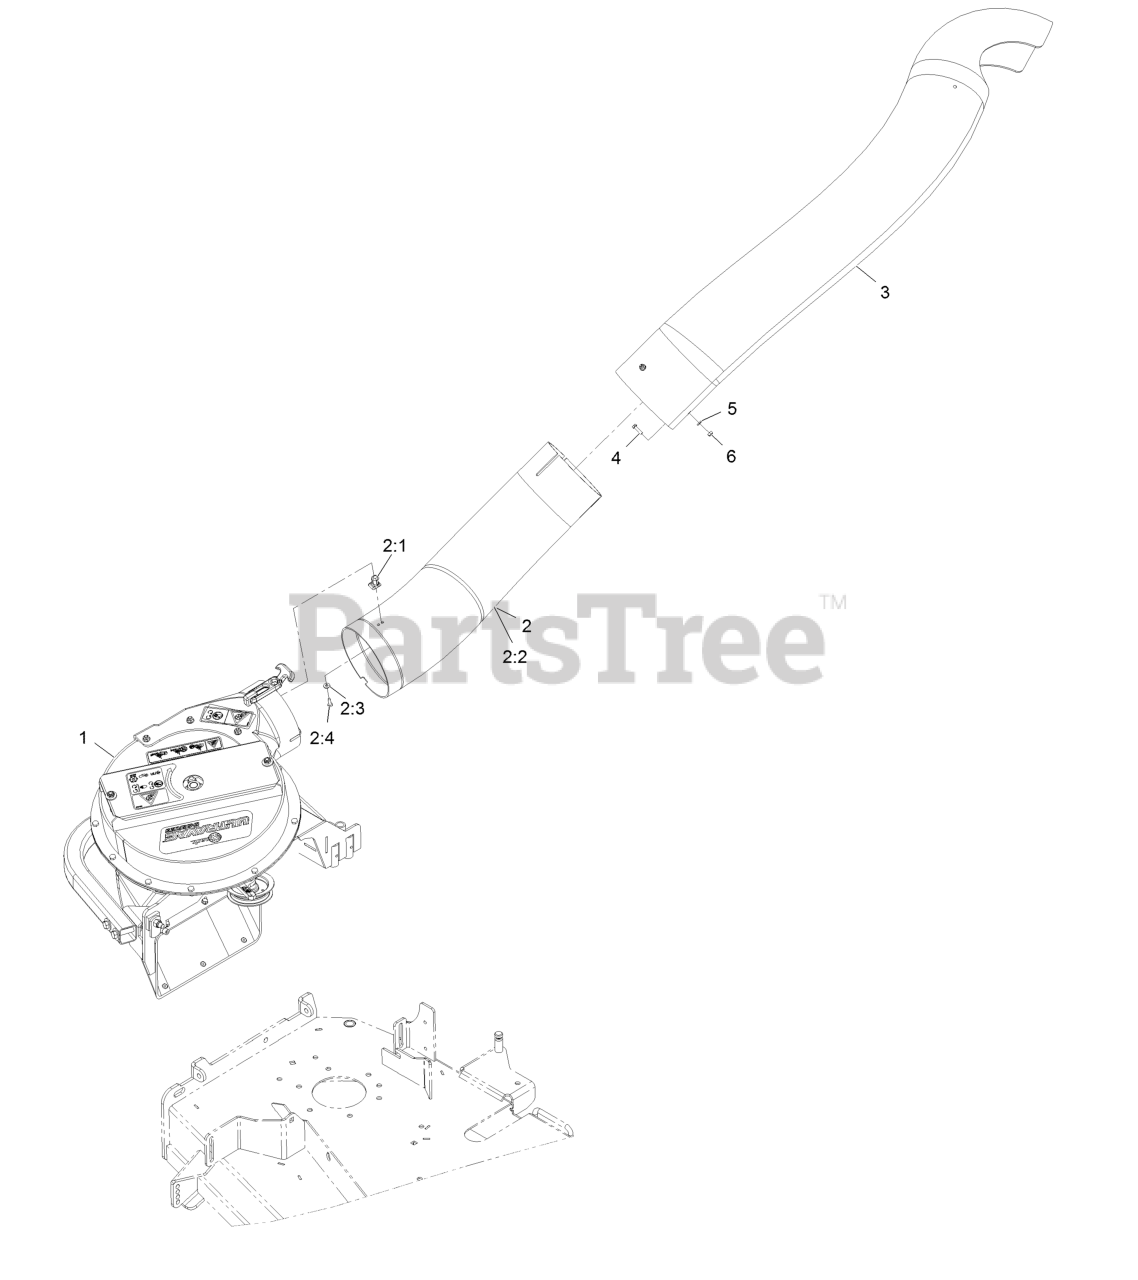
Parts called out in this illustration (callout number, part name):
1	ASM- BLOWER
2	LOWER TUBE ASM
2:1	Tube-Lower, Short
2:2	LATCH-KEEPER
2:3	SCREW-PPH
2:4	WASHER-FLAT
3	TUBE-UPPER
4	SCREW-HWH
5	WASHER-FLAT
6	NUT-LOCK, NI
